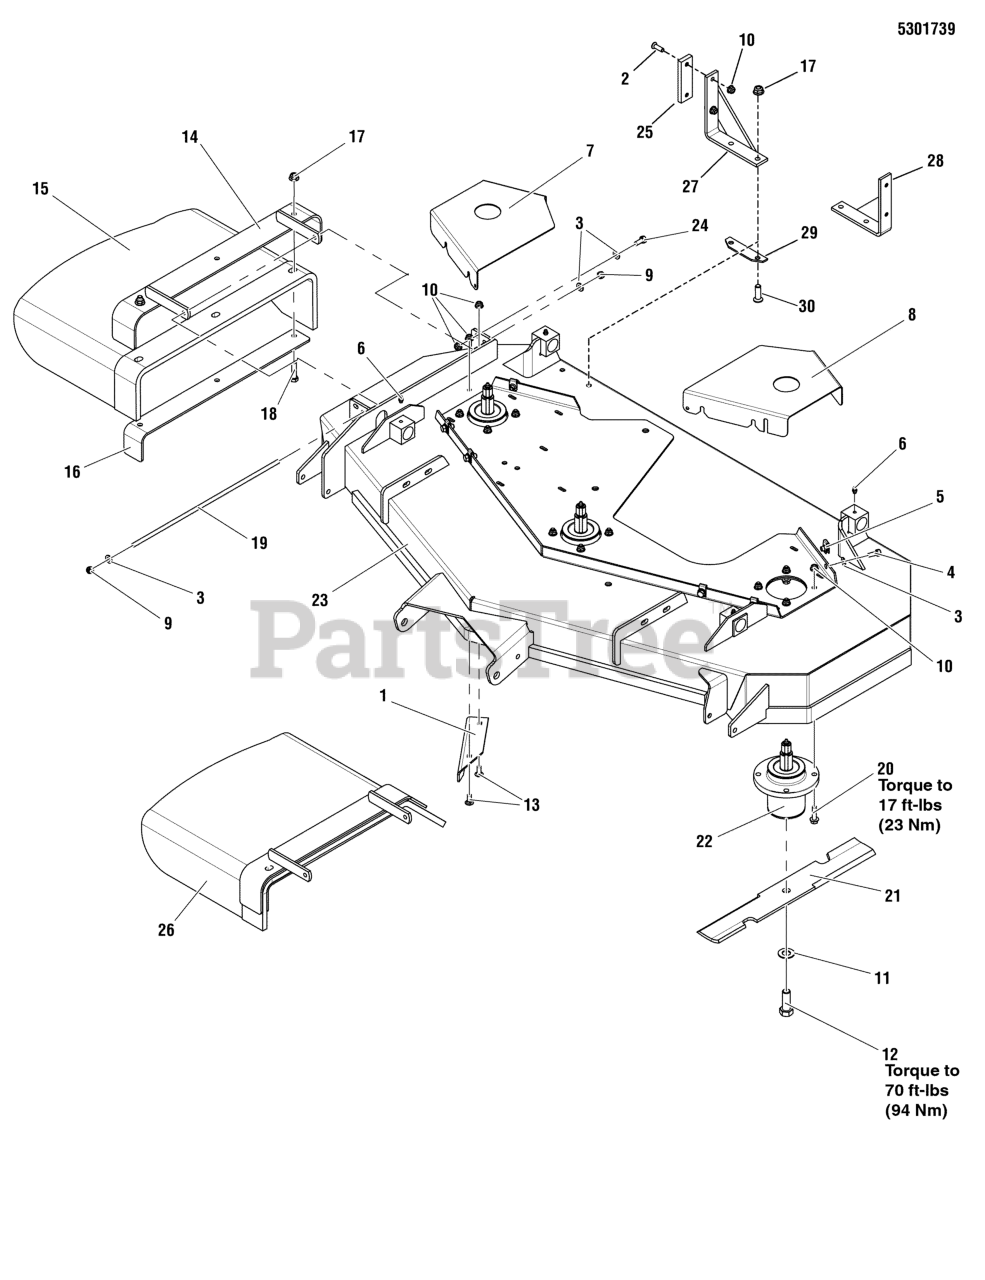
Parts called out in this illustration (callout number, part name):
1	PLATE, DEFLECTOR - BLK
2	SCREW, 5/16-18 X 1, PHILLIPS HD, BZ
3	WASHER, 5/16" SAE
4	BOLT, 5/16-18 X 3/4 GD5
5	BODY CLIP, 5/16-18-7GA MATERIAL
6	GREASE FITTING, 1/4-28 STRAIGHT
7	GUARD, DECK, 52, RH, SW20 - RED
8	GUARD, DECK, 52, LH, SW20 - RED
9	NUT, 5/16-24 HEX NYLON LOCK
10	NUT, 5/16-18 HEX NYLOCK FLANGE
11	WASHER, 5/8 GRADE 8, YZ
12	BOLT, 5/8-11 X 1-3/4 GD8
13	BOLT, 5/16-18 X 3/4, CARRIAGE
14	WELD, MOUNT, DISCHARGE CHUTE - BLK
15	CHUTE, DISCHARGE, BEND RUBBER 52"
16	SUPPORT,DISCHARGE CHUTE - BLK
17	NUT, 3/8-16 HEX NYLCK FLG
18	BOLT, 3/8-16 X 1-1/2" GD5 CZ
19	ROD, 5/16 X 13.75, TBE
20	BOLT, 5/16-18 X 1 1/4 FLANGE
21	BLADE, SET OF THREE
22	ASSM, SPINDLE, LOW PROFILE
23	DECK SHELL W/ DECALS, 52, SW30
23	DECK SHELL W/ DECALS, SW30 52
24	BOLT, 5/16-18 X 3/4 GD5
25	PAD, FRICTION, .375 X 1.25 X 4.00
26	KIT, DISCHARGE CHUTE, 44/48/52
27	WELD, FRICTION PAD HOLDER, RH - RED
28	WELD, FRICTION PAD HOLDER, LH - RED
29	PLATE, BRACKET SUPPORT - RED
30	BOLT, Carriage, 3/8-16 X 1
